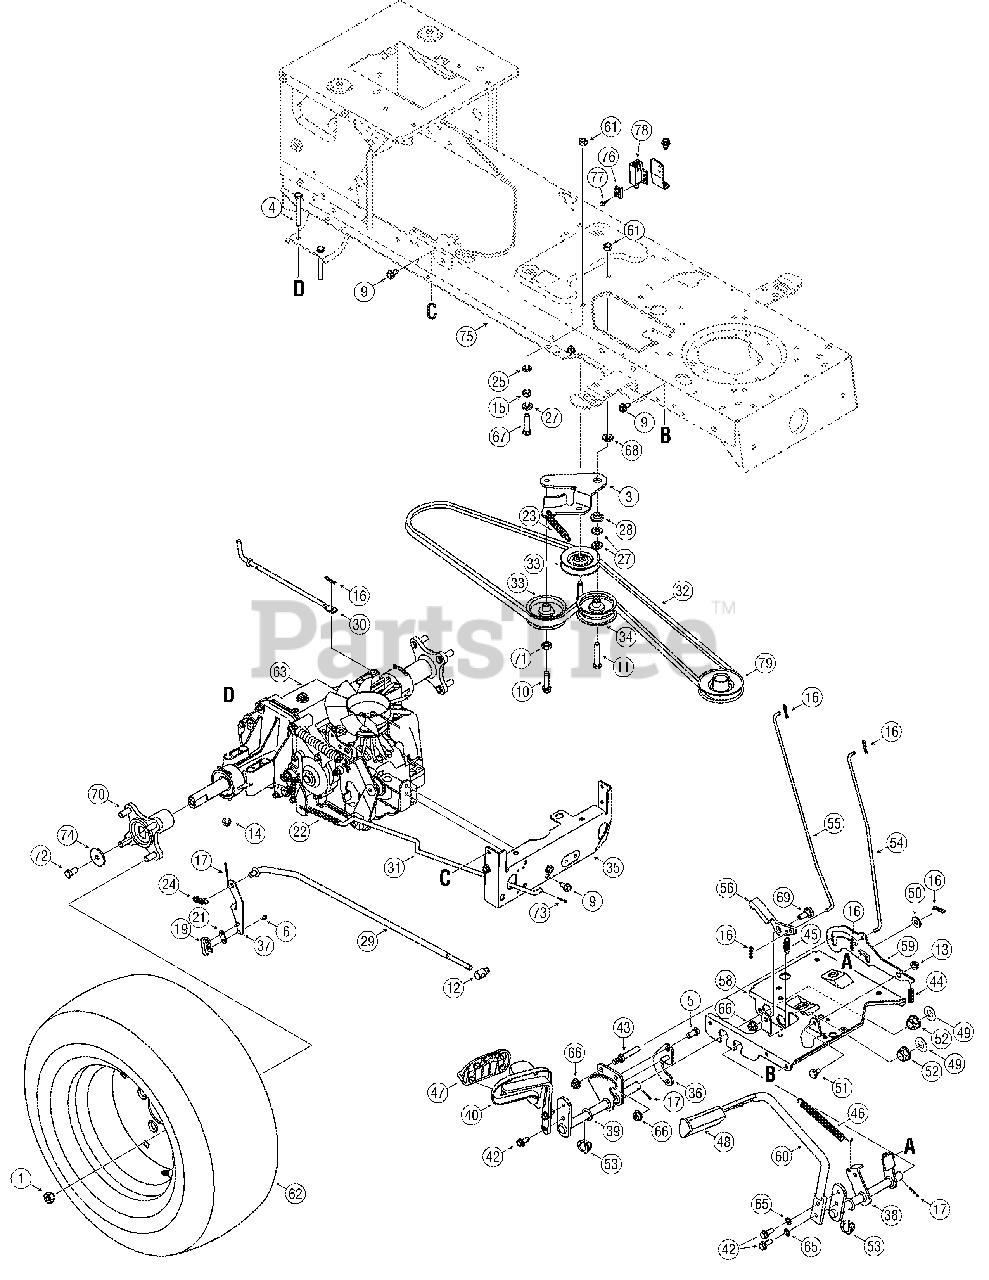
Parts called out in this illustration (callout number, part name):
1	Lug Nut, 3/4-16
2	Revse./Grnd. Wire Harness Adptr.
4	Hex Cap Screw, 5/16-18 x 2.75
5	Hex Cap Screw, 3/8-16 x.75
6	Screw, #8-18 x.5
7	Hex Cap Screw, 3/8-16 x 1.5
8	Self-tapping Screw, 1/4-20 x.50
9	Self-tapping Screw, 5/16-12 x.75
10	Hex Cap Screw, 3/8-16 x 2.25
12	Ferrule, 3/8-24
13	Flange Lock Nut, 5/16-18
14	Flange Lock Nut, 5/16-18
15	Hex Nut, 3/8-16
16	Internal Cotter Pin
19	Short Spring Switch
21	Insulator Nut Plate
22	Extension Spring,.59 x 4.0
23	Extension Spring,.770 x 3.72 Lg.
24	Extension Spring, 3/8 x 1.44
25	Lock Washer, 3/8
26	Flat Washer,.344 x.750 x.120
27	Flat Washer .406 x .875 x .059
28	Shoulder Spacer,.38
29	Hydrostatic Control Rod
30	Hydrostatic Bypass Rod
31	Hydrostatic Brake Rod
32	Drive Belt
33	V-idler Pulley, 3.06
34	Flat Idler Pulley, 2.75
41	Self-tapping Screw, 5/16-18 x.875
42	Self-tapping Screw, 5/16-18 x.75
43	Pin, 3/8-16 x 2.43
44	Compression Spring,.40 OD x 1.17
45	Extension Spring,.50 OD x 1.41
46	Extension Spring,.50 OD x 6.37
47	Drive Pedal Pad
48	Brake Pedal Pad
49	Flat Washer,.64 x 1.24 x.06
50	Flat Washer,.385 x.870 x.092
51	Shoulder Screw,.437 x 1.62
52	Hex Flange Bearing
53	Split Hex Flange Bearing
54	Brake Lock Control Rod
55	Cruise Control Rod
57	Spacer, 5/16 x 1.54
59	Drive Lockout Bracket
61	Hex Nut, 3/8-16
63	Hydrostatic Transmission Assmbly
64	Self-tapping Screw, 5/16-18 x.75
65	Lock Washer, 5/16
66	Flange Lock Nut 3/8-16
67	Hex Cap Screw, 3/8-16 x 1.5
68	Flat Washer.385 x 1.00 x.135
69	Shoulder Screw 3/8-16.50 x.27
70	Wheel Hub Assembly
71	Jam Nut, 7/16-20
72	Screw, 3/8-16 x.750
74	Flat Washer,.390 x 1.500 x.134
77	Screw, #10-16
78	Interlock Switch
79	Electric PTO Pulley
